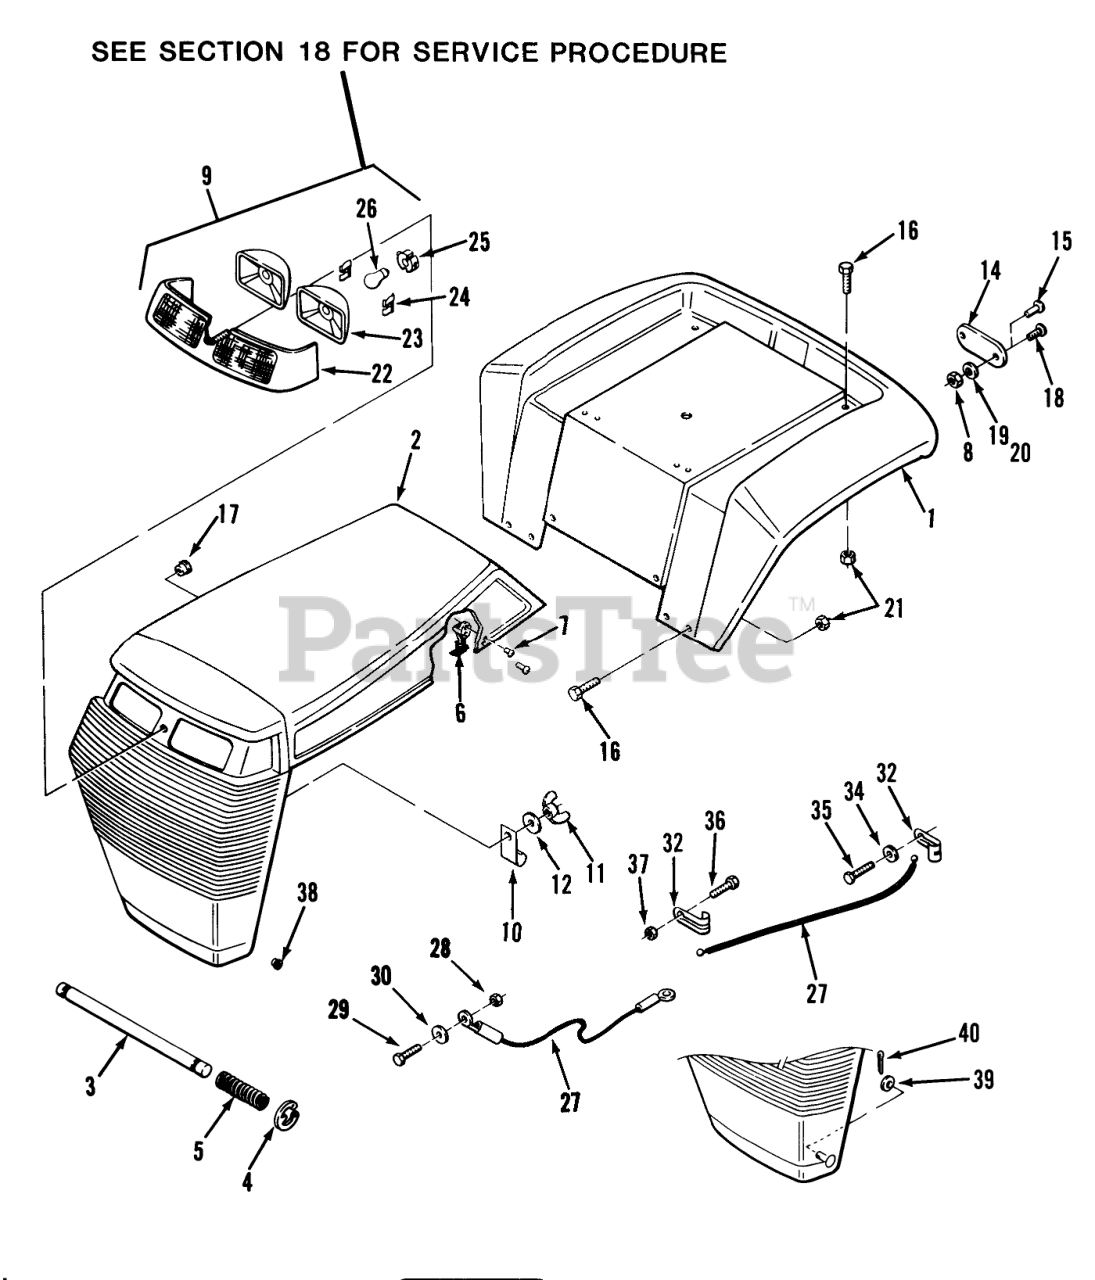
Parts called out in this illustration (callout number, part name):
1	FENDER R
2	Hood & Grill 210-s
4	E-Ring
5	SPRING
6	KEEPER-LATCH
7	POPRIVET 1/8X 1/8 BK
8	Nut
9	Head Light Bar (Includes items 22, 23, 24 & (2) of 26)
10	J-CLIP
11	Nut-Wing
12	WASHER
14	Reflector
15	Poprivet
16	Bolt-Carriage
17	BUSHING-NYLON 1.093
18	Screw
19	WASHER
20	Lockwasher
21	Nut
22	LIGHT-BAR BLACK
23	LIGHT POD
24	RETAINER
25	SOCKET-HEADLIGHT
26	BULB
27	CABLE-HOOD LANYARD
28	E.S. Nut #10-24
29	Screw-Machine
30	WASHER-BACKING
32	CLEVIS
34	Washer
35	Bolt
36	Screw-Machine
37	Nut
38	Nyliner Bushing (Only 2 used on 212-s)
39	WASHER 5/16 SAE
40	Cotter Pin
